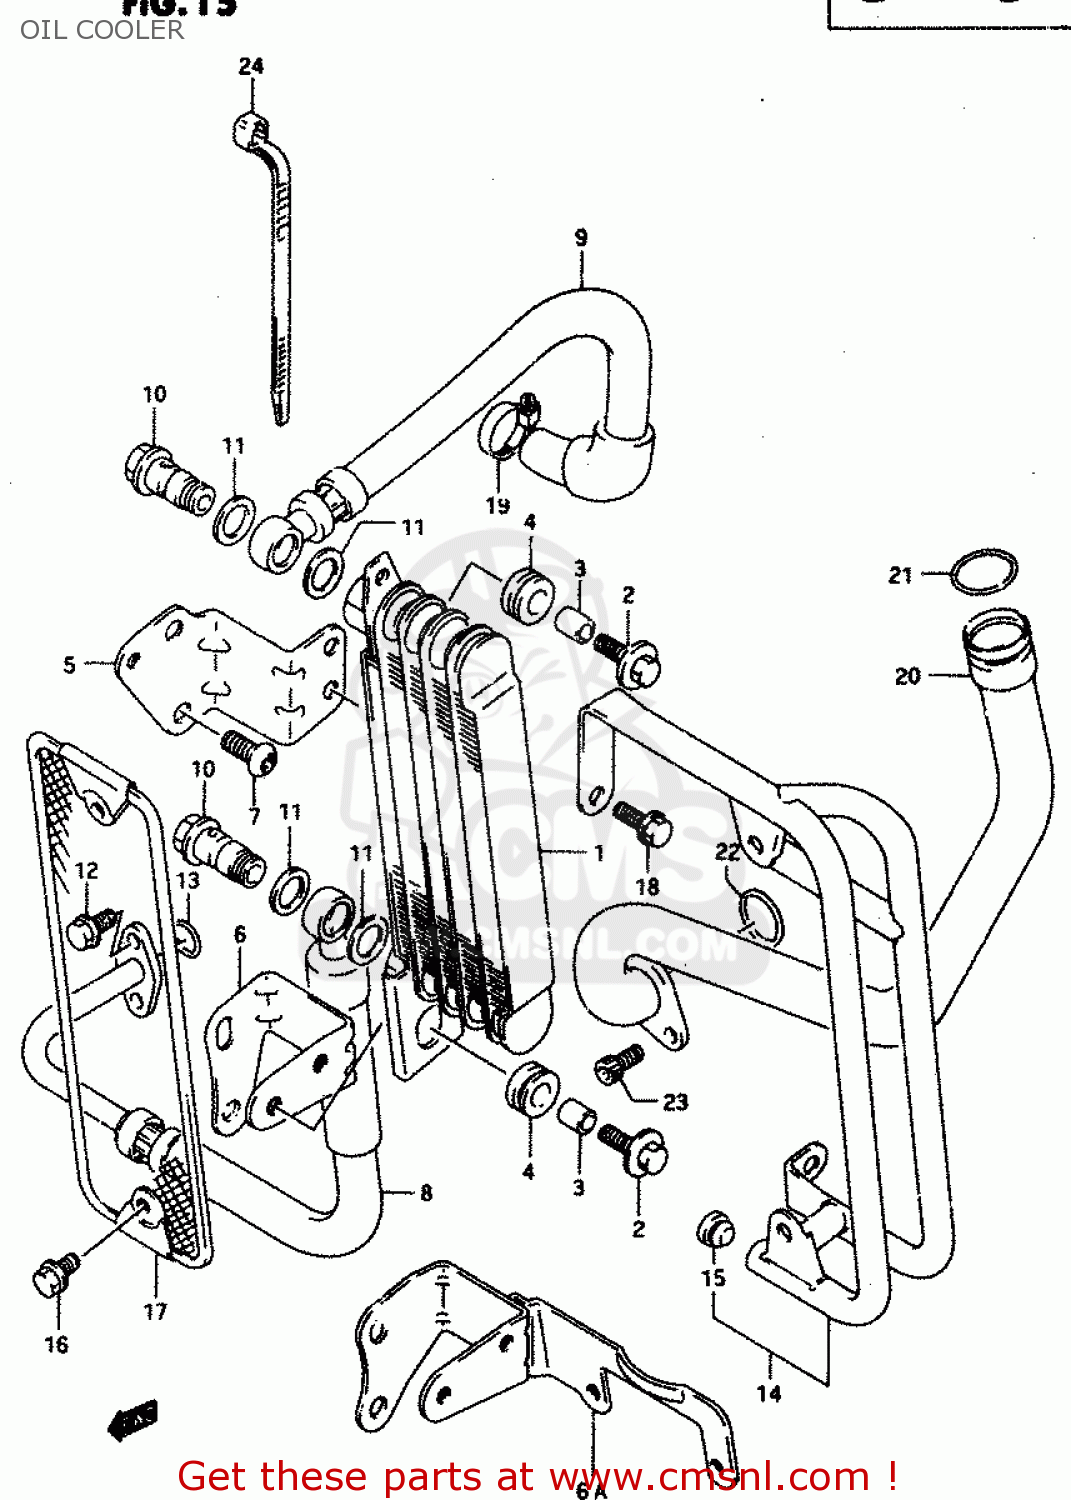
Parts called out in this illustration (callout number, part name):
1	COOLER ASSEMBLY,OIL
2	BOLT 6X20
3	SPACER (6.8X10X10)
4	CUSHION
5	BRACKET,OIL COOLER UPR
6	BRACKET,OIL COOLER,LOWER
6A	BRACKET COMP,OIL COOLER
7	BOLT(8X12)
8	HOSE,OIL COOLER NO.1
9	HOSE,OIL COOLER NO.2
10	BOLT UNION
11	GASKET(14X20X1.5) (NAS)
12	BOLT
13	O RING(D:2.4,ID:12.3)
14	GUARD,OIL COOLER
15	PLUG(OD:13)
16	BOLT
17	BUMPER,OIL COOLER
18	BOLT
19	CLAMP
20	PIPE COMP,OIL RETURN
21	O RING(D:3.7,ID:21.7)
22	O-RING (D:2.4 ID:23.7)
23	BOLT,OIL FILLE
24	CLAMP(L:125)
